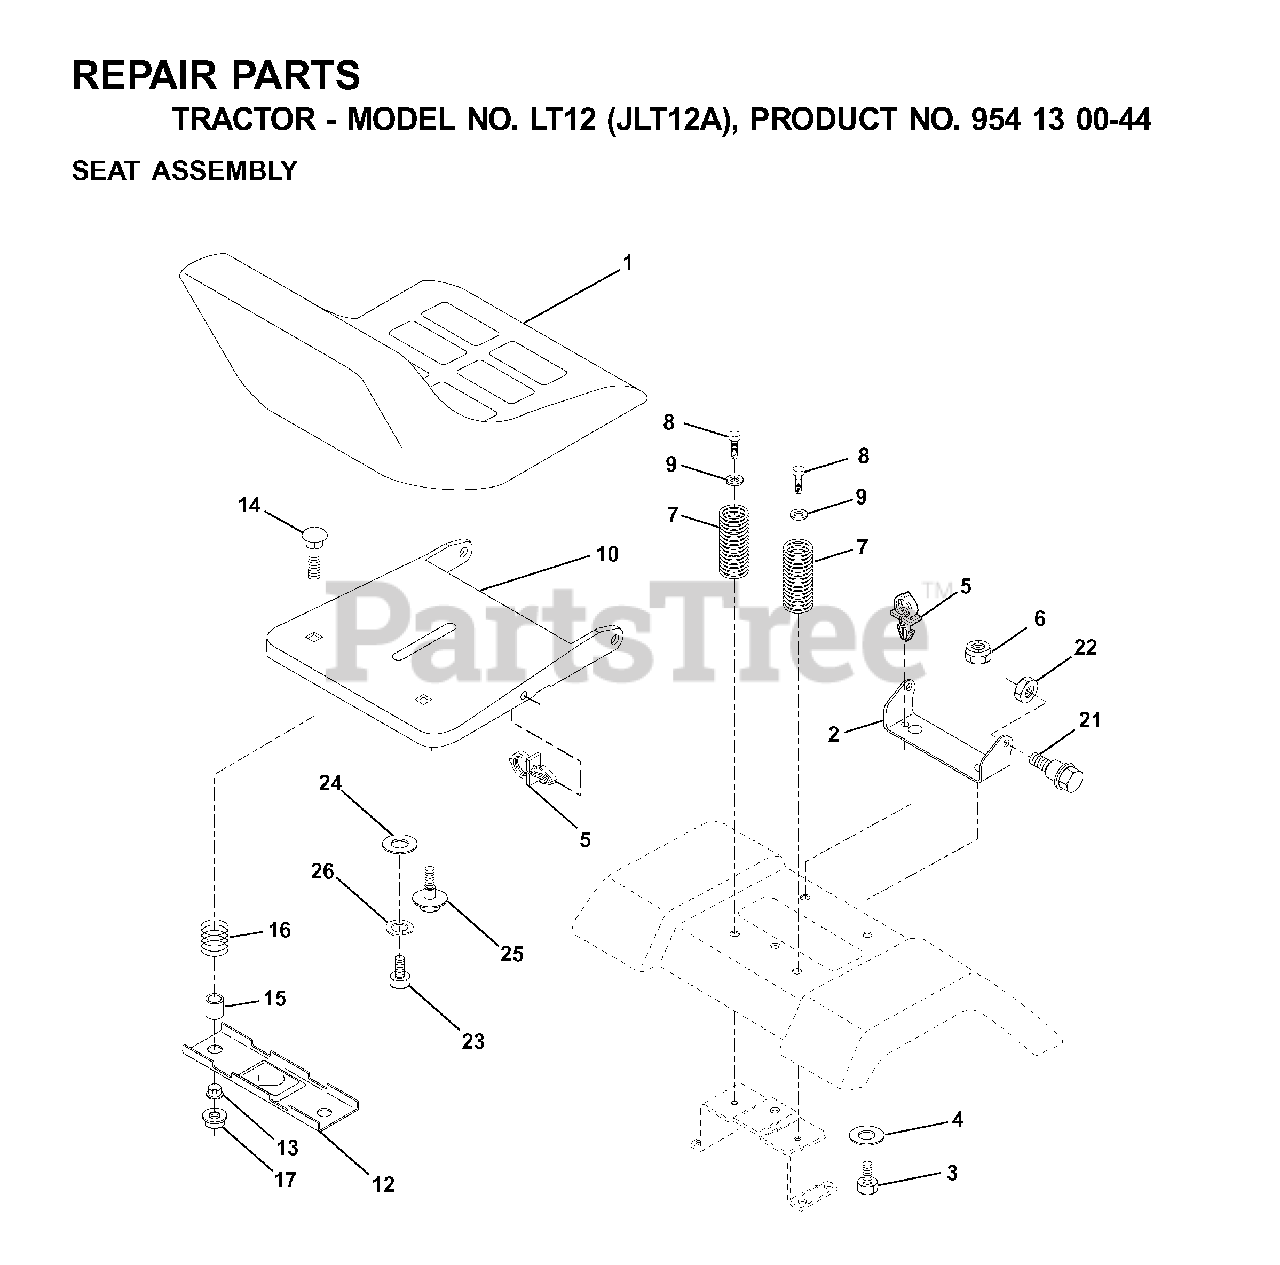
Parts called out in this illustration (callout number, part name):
1	SEAT
2	SEAT PIVOT BRKT
4	WASHER PM
5	PUSH CLIP
6	NUT
7	SPRING COMPRESSION
8	SCREW 3/8-16X1
9	WASHER
10	PAN, SEAT
12	BRKT SWITCH
14	BOLT.ROUND.HEAD.SQUARE.NECK
15	SPACER SPLIT 28X.96
17	NUT T
21	BOLT.SHOULDER.5/16-18
22	NUT.71038.31-18.HEX.NYLOCK
23	BOLT.HEX.BLACK
25	BOLT,SHOULD
26	LOCKWASHER
